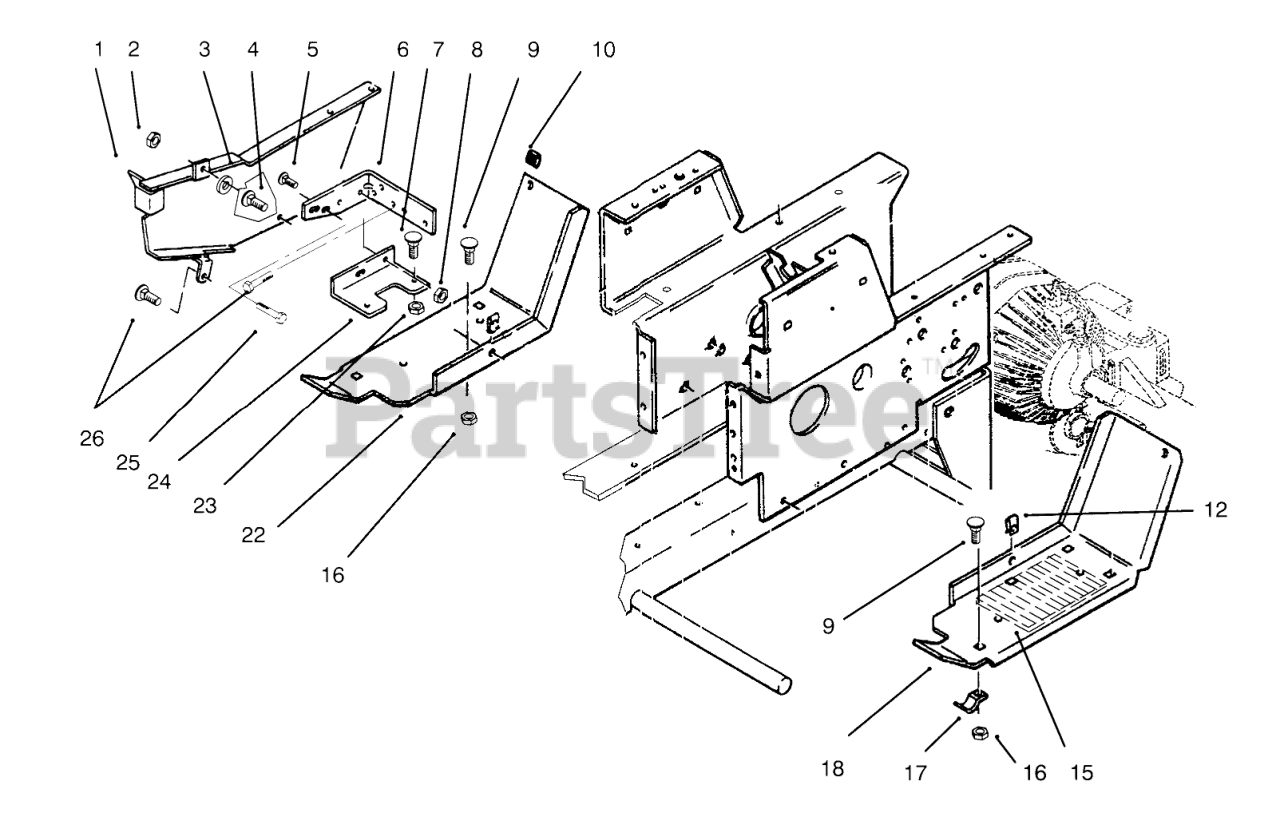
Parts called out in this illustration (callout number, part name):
1	GUARD - BELT WA R
2	NUT-LOCK, NI
3	NUT-PUSH
4	Screw
5	SCREW-HH
6	BRACKET-BELTB
8	NUT-LOCK, NI
9	BOLT-CARR
10	BUMPER
15	PAD FOOTREST
16	NUT-LOCK, NI
17	BRACKET
18	FOOTREST LH R
22	Footrest-RH
23	Nut
24	BRKT-FUS HLDERB
25	BOLT-CARR
26	SCREW
